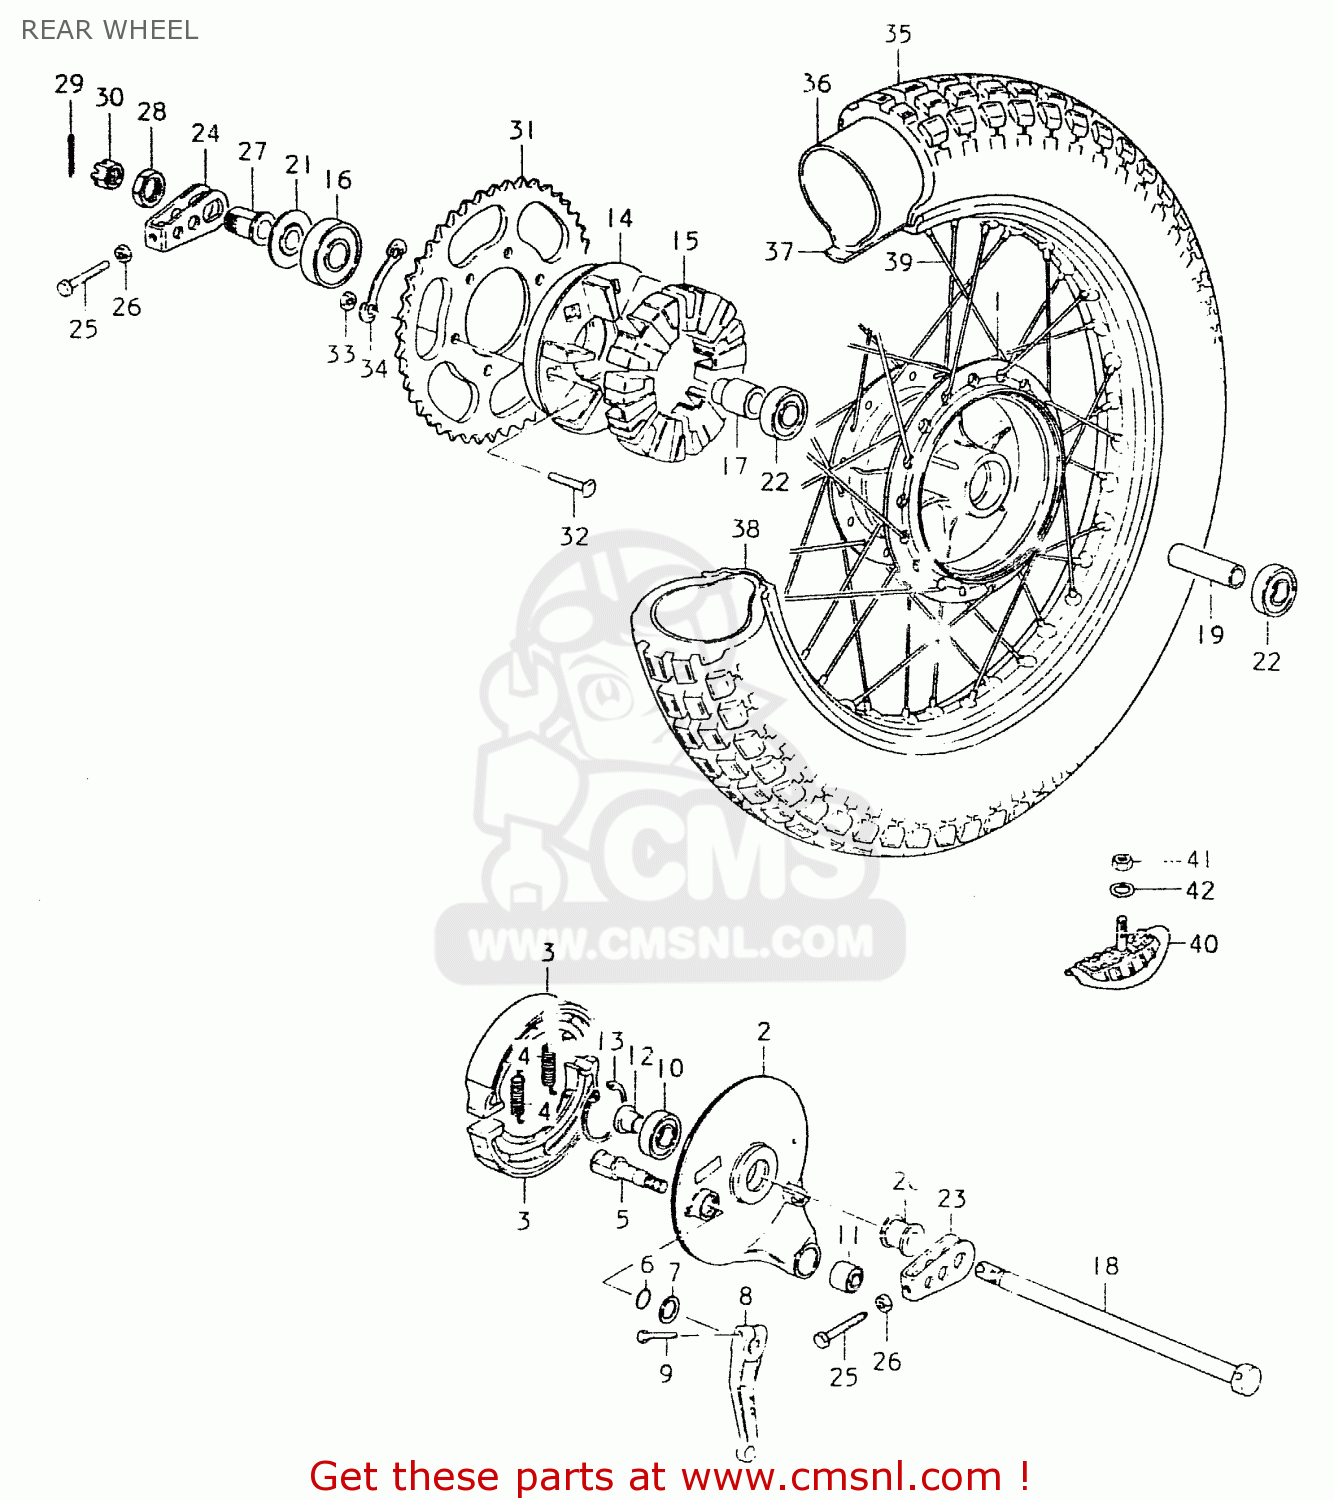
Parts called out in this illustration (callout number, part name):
1	DRUM,REAR HUB
2	PANEL,REAR HUB
3	SHOE,BRAKE (MCA)
4	SPRING
5	CAM,FRONT BRAKE
6	O-RING,BOSS
7	WASHER (15X24X1.6)
8	LEVER,REAR BRAKE CAM
9	BOLT
10	BALL BEARING
11	BUSH
12	SPACER,REAR HUB PANEL
13	CIRCLIP,42MM
14	DRUM,REAR SPROCKET MOUNT
15	CUSHION,REAR DRUM
16	BEARING
17	SPACER,REAR HUB BEARING
18	AXLE,REAR
19	SPACER (15.3X21.7X82)
20	SPACER,AXLE,RIGHT
21	SPACER,REAR AXLE,RIGHT
22	BEARING, RH
23	ADJUSTER,CHAIN
24	ADJUSTER,CHAIN
25	BOLT
26	NUT
27	SPACER,CHAIN ADJUSTER
28	NUT
29	PIN 30X40
30	NUT
31	SPROCKET,REAR
32	BOLT(8X33.5)
33	NUT
34	WASHER
35	TIRE
36	TUBE,INNER
37	PROTECTOR,WHEEL,INNER
38	RIM,REAR WHEEL
39	SPOKE SET,RR
40	STOPPER,BEAD
41	NUT
42	WASHER
